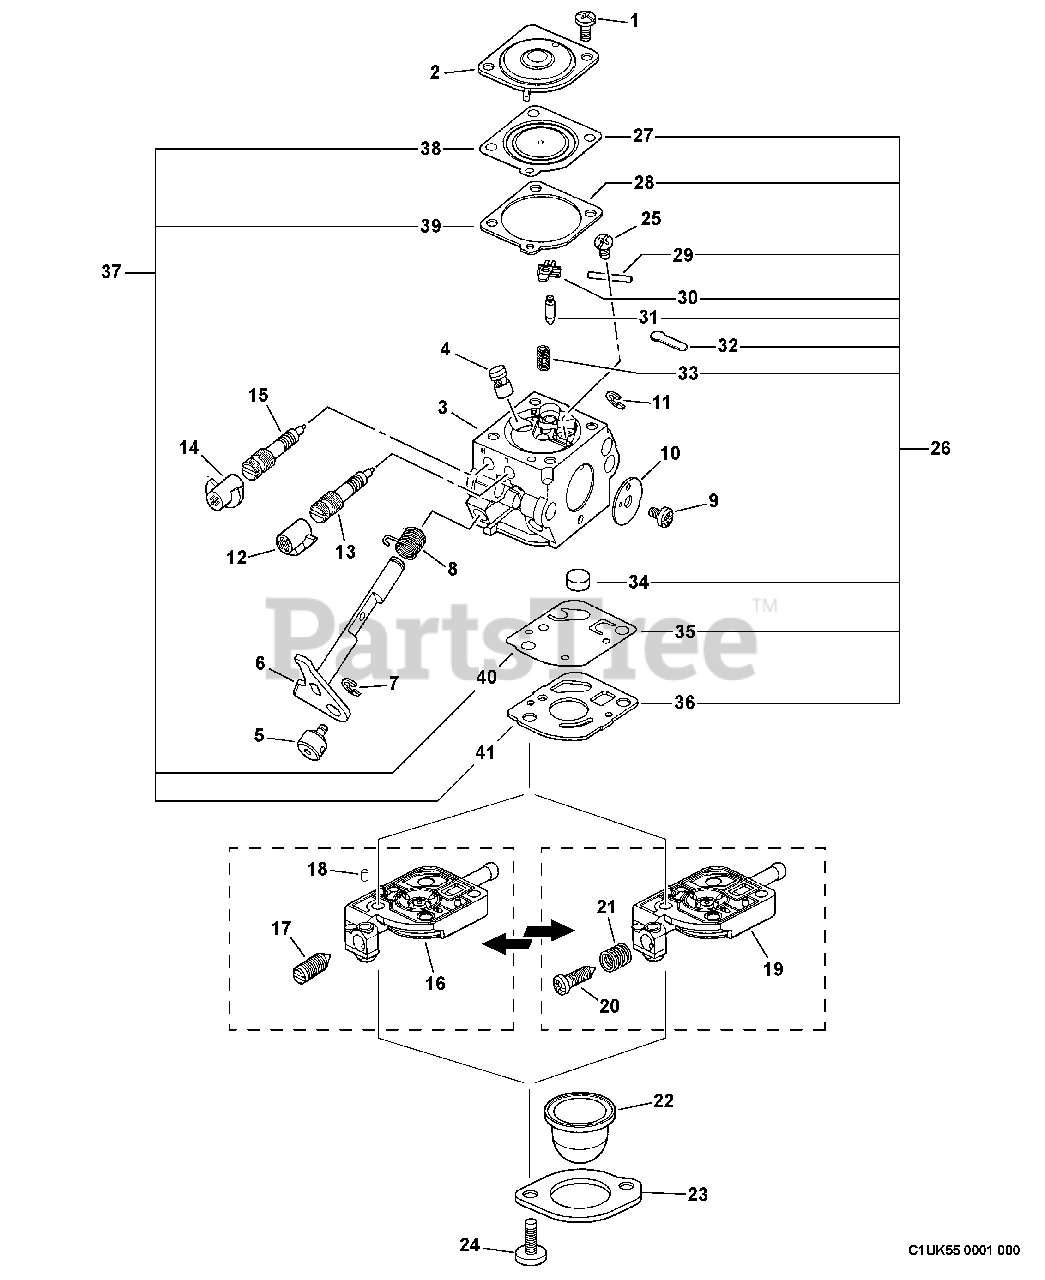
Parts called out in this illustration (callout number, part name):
2	COVER, METERING DIAPHRAGM
3	BODY, CARBURETOR
4	NOZZLE, CHECK VALVE
6	SHAFT, THROTTLE
8	SPRING, THROTTLE RETURN
10	VALVE, THROTTLE
12	CAP, LIMITER - WHITE
13	SCREW
14	CAP, LIMITER - RED
15	NEEDLE, HIGH SPEED
16	BODY ASSY, PURGE
17	SCREW, IDLE ADJUST
18	PIECE, FRICTION
19	BODY ASSY, PURGE
20	SCREW, THROTTLE ADJUST
22	BULB, PURGE
23	RETAINER
26	REPAIR KIT, CARBURETOR
27	DIAPHRAGM, METERING
28	GASKET, DIAPHRAGM
29	PIN, METERING LEVER
30	LEVER, METERING
31	VALVE, INLET NEEDLE
32	PLUG, WELCH
33	SPRING, METERING LEVER
34	STRAINER
35	DIAPHRAGM, PUMP
36	GASKET, PUMP
37	GASKET / DIAPHRAGM KIT
38	DIAPHRAGM, METERING
39	GASKET, DIAPHRAGM
40	DIAPHRAGM, PUMP
41	GASKET, PUMP
